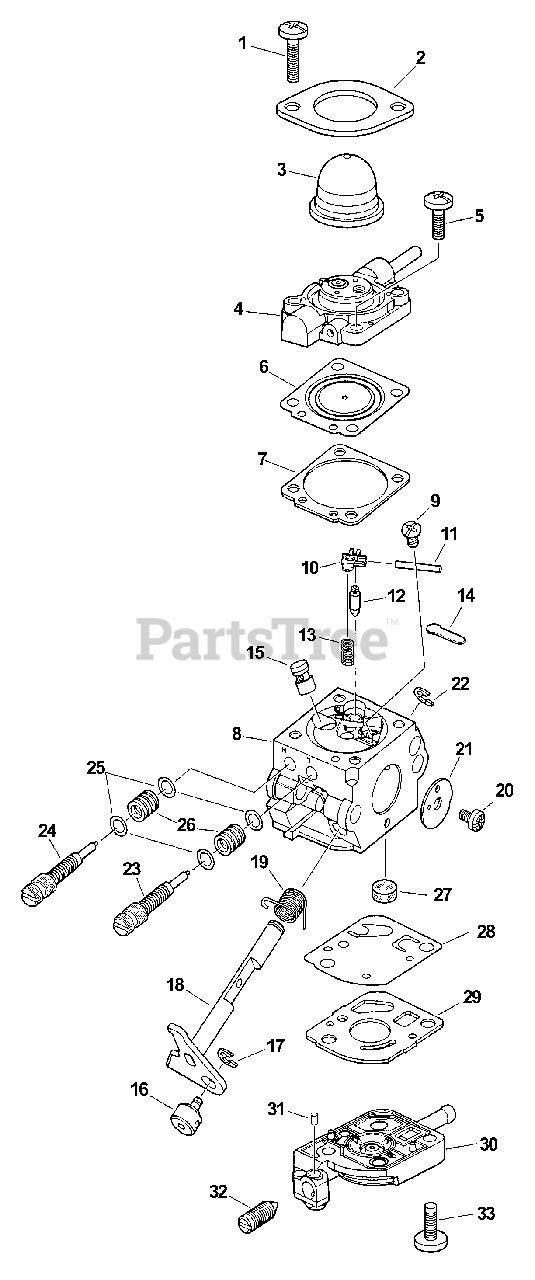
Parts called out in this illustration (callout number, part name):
1	SCREW, RETAINER
2	RETAINER, PURGE BULB
3	BULB, PURGE
4	BASE, PURGE
5	SCREW, PURGE BASE
6	DIAPHRAGM, METERING
7	GASKET, METERING
8	BODY, CARBURETOR
9	SCREW, METERING LEVER PIN
10	LEVER, METERING
11	PIN, METERING LEVER
12	VALVE, INLET NEEDLE
13	SPRING, METERING LEVER
14	PLUG, WELCH
15	NOZZLE, CHECK VALVE
17	RING, RETAINING
18	SHAFT, THROTTLE
19	SPRING, RETURN
21	VALVE, THROTTLE
22	RING, RETAINING
23	NEEDLE - LOW SPEED
24	NEEDLE - HIGH SPEED
27	STRAINER
28	DIAPHRAGM, PURGE
29	GASKET, PURGE
30	BASE, PURGE
31	PIECE, FRICTION
32	SCREW, IDLE ADJUST
33	SCREW, PUMP COVER
